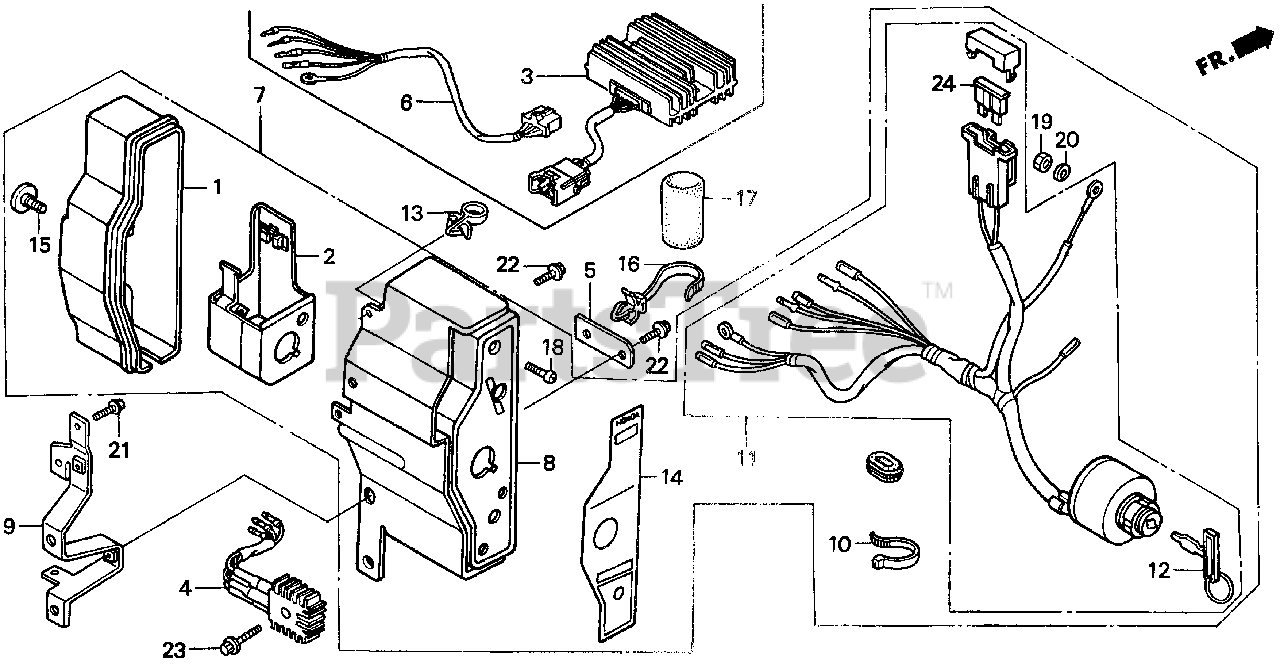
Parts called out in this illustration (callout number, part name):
1	CASE, CONTROL
2	BRACKET, CASE MOUNTING
3	RECTIFIER ASSY., REGULATOR (20A)
5	BRACKET, WIRE HARNESS CLIP
6	SUB-WIRE HARNESS ASSY.
7	BOX ASSY., CONTROL
8	PANEL, CONTROL
9	STAY, CONTROL BOX
10	BAND
11	SWITCH ASSY., COMBINATION
12	KEY
13	HOLDER, STOP SWITCH WIRE
14	MARK, CONTROL BOX (EXTERNAL-REGULATOR)
15	SCREW, SPECIAL (6X12)
16	BAND, WIRE HARNESS (150MM) (BLUE)
17	TUBE, CORD (30MM)
18	SCREW, PAN (4X12)
19	NUT, HEX. (4MM)
20	WASHER, SPRING (4MM)
21	BOLT, FLANGE (6X10)
22	BOLT, FLANGE (6X12)
24	FUSE, BLADE (25A)
